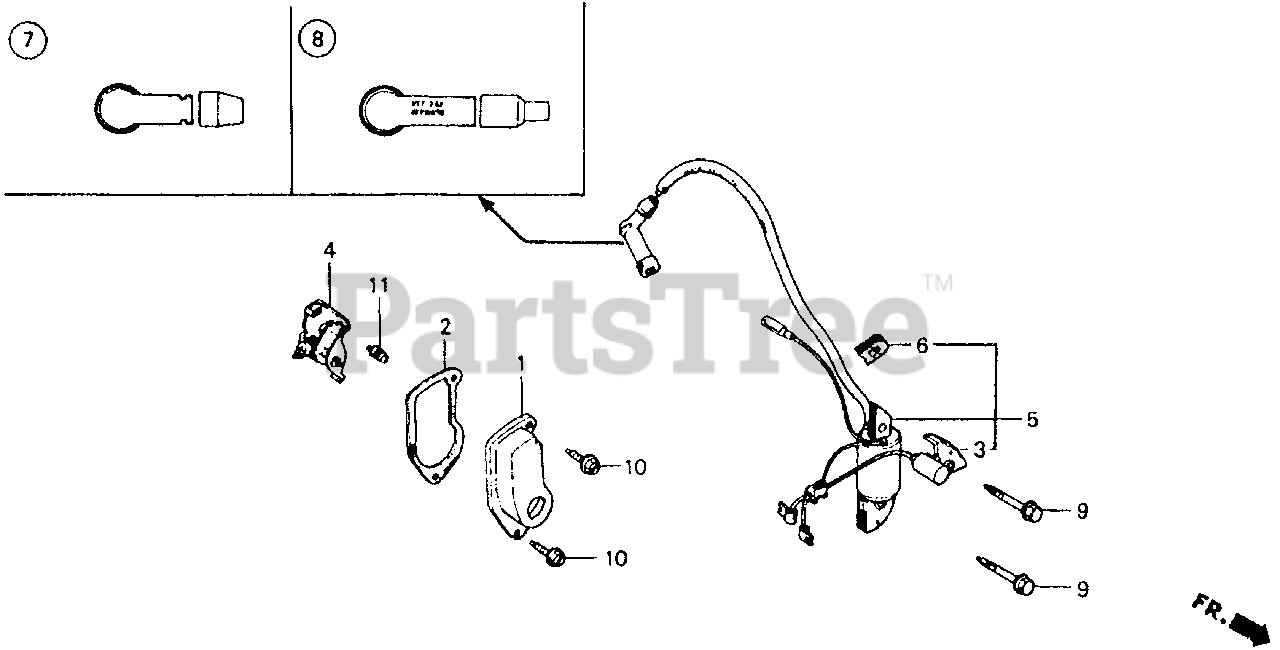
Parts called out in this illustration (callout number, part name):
1	COVER, POINTS
2	GASKET, POINT COVER
3	CONDENSER
4	POINTS ASSY.
5	COIL ASSY., IGNITION
6	GROMMET, WIRE
7	TERMINAL ASSY., IGNITION
9	BOLT, FLANGE (6X32)
10	BOLT, FLANGE (5X10)
11	SCREW-WASHER (5X12)
